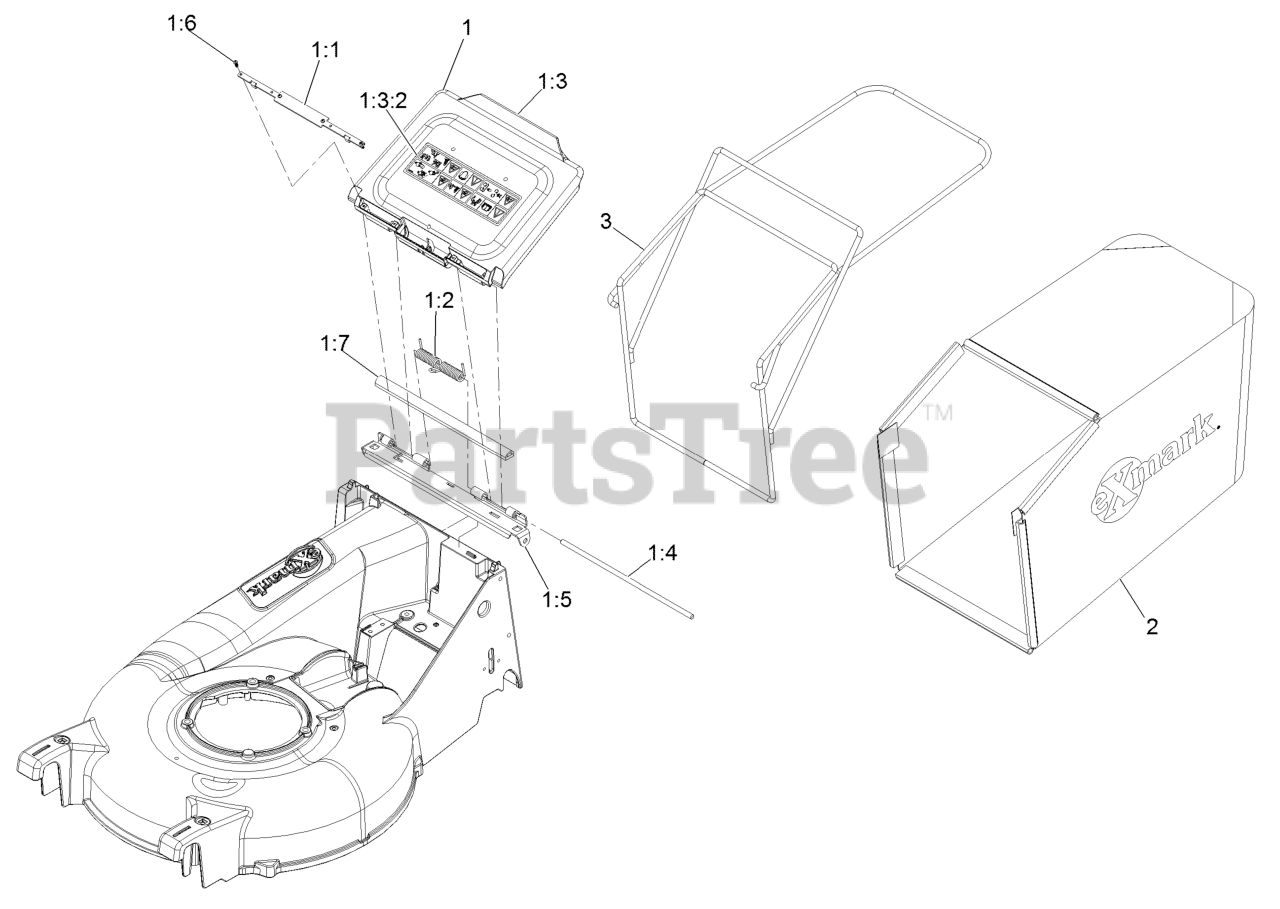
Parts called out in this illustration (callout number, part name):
1	DOOR ASM
1:1	PLATE, DOOR COVER
1:2	SPRING-PLASTIC DOOR
1:3	ASM-DOOR & DECAL
1:3:2	DECAL-WARNING
1:4	PIN-DOOR PIVOT
1:5	BRACKET-DOOR PIVOT
1:6	SCR,TAP,6-19X7/16,PHPH, S
1:7	SEAL-EPDM FOAM BULB
2	BAG-21 GRASS
3	WLD-BAG FRAME
